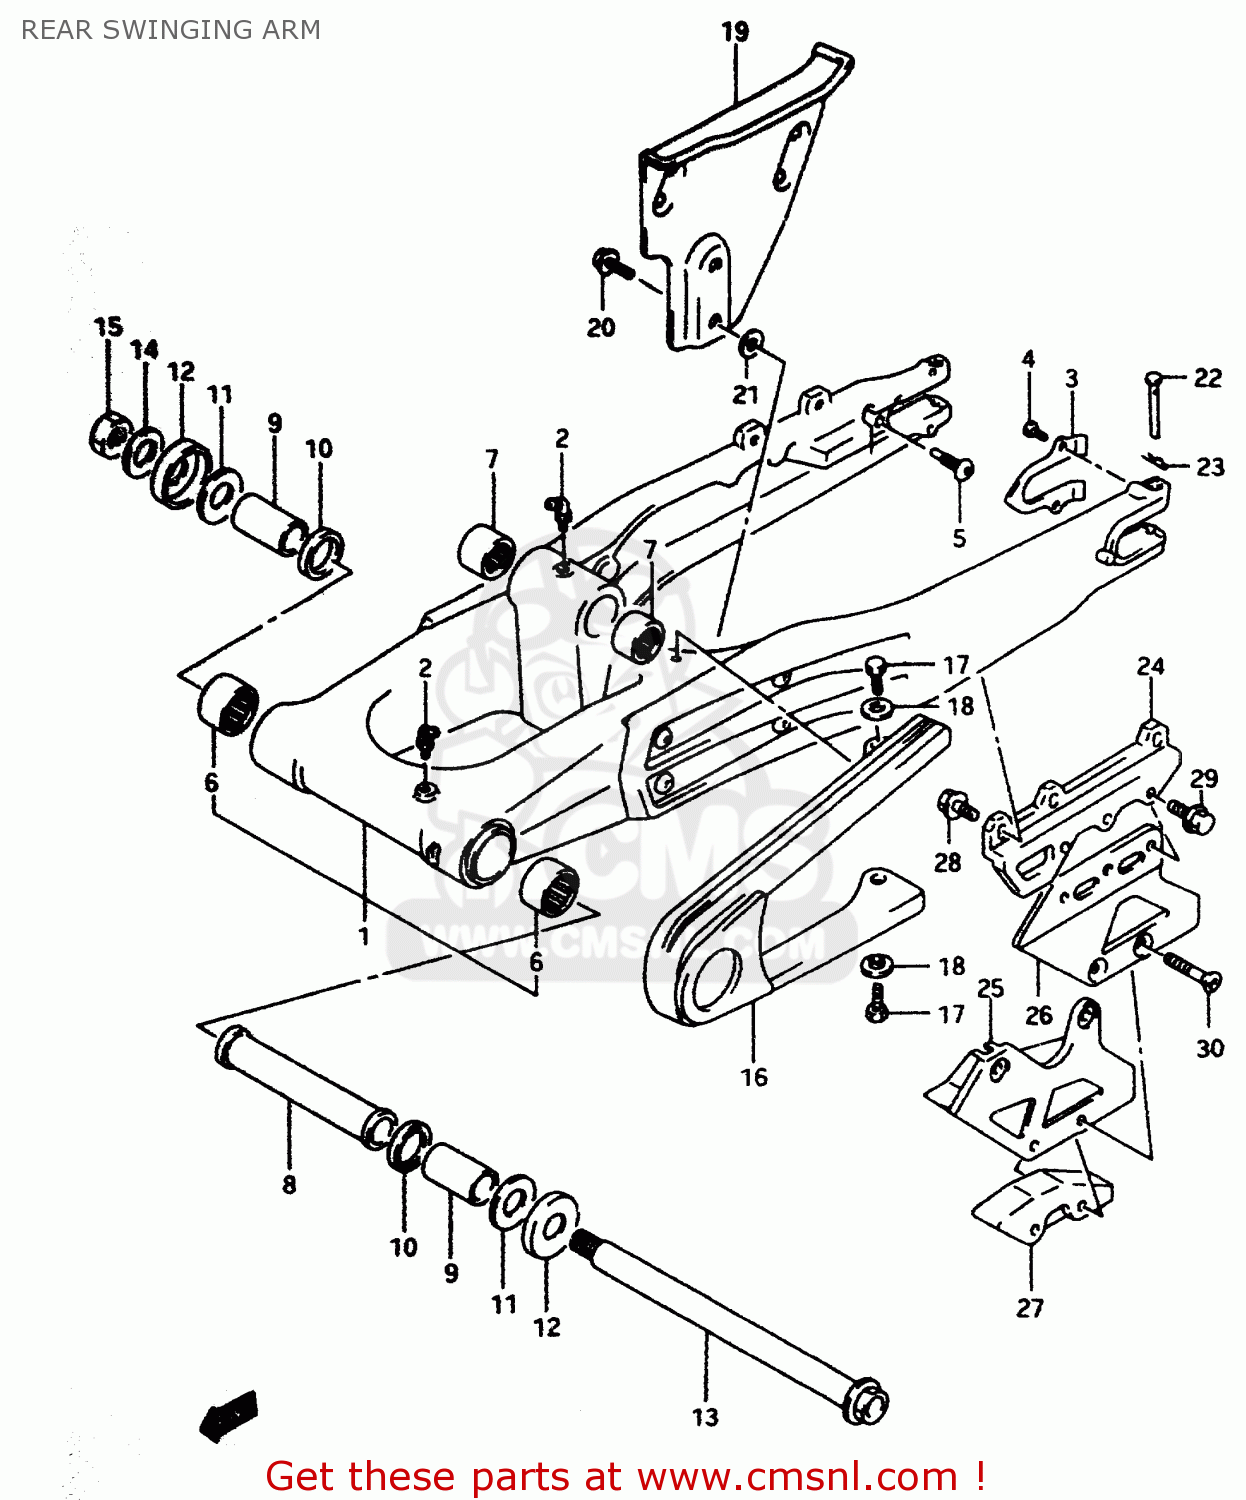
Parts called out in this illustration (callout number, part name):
1	SWING ARM ASSEMBLY,REAR
2	NIPPLE,GREASE
3	PLATE,SWING ARM RR
4	SCREW (5X8)
5	SCREW (M10X21)
6	BEARING(22X29X30)
7	BEARING(20X27X23.5)
8	SPACER,SWING ARM PIVOT,CENTER
9	SPACER,SWGARM PIVOT BRG
10	SEAL,OIL(22X29X4)
11	WASHER
12	COVER,SWINGINGARM PIVOT
13	SHAFT,SWINGING ARM PIVOT
14	WASHER, FIXED DRIVE FACE
15	NUT
16	BUFFER,CHAIN TOUCH DEFENSE
17	BOLT
18	WASHER
19	GUARD,CHAIN
20	BOLT
21	WASHER
22	PIN
23	CLIP
24	BRACKET,CHAIN GUIDE
25	GUIDE,CHAIN
26	PLATE,CHAIN GUIDE OUTER
27	DEFENSE,CHAIN GUIDE
28	BOLT
29	SCREW
30	SCREW(6X40)
